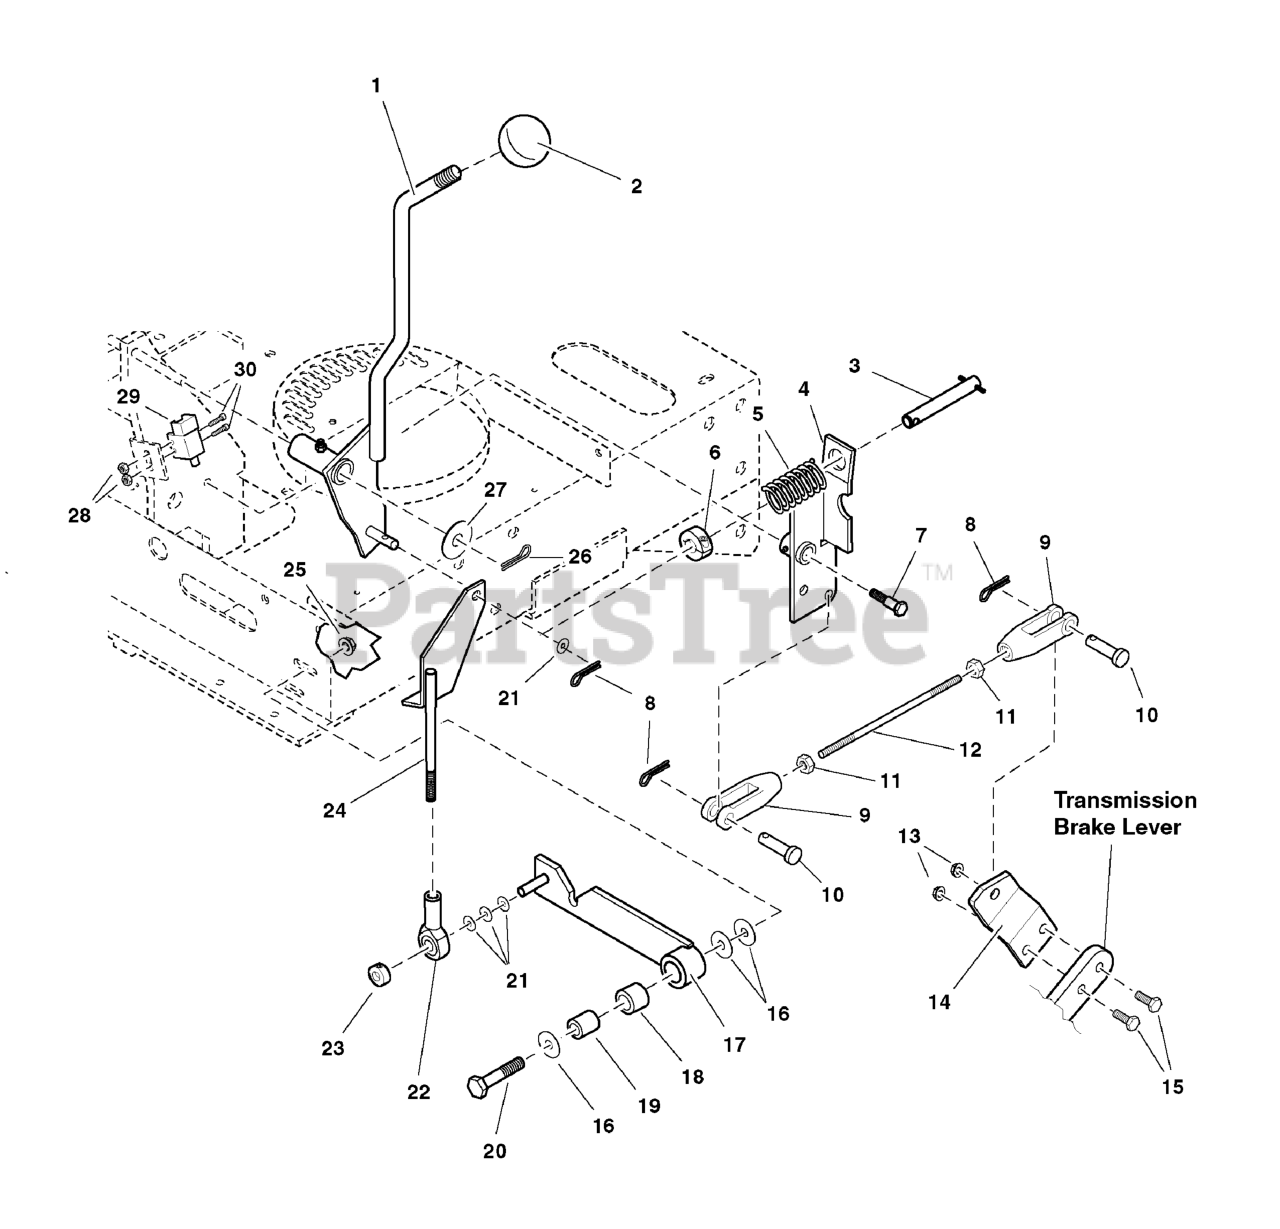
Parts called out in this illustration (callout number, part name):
1	PARKING BRAKE LEVER
2	KNOB
3	SPRING BAR ASSEMBLY
4	BRAKE ROCKER ARM
5	SPRING, Compression
6	COLLAR, 5/8" Set
7	SHOULDER BOLT, 1/2 x 1
8	PIN, 3/32 X 0.750, COT, ZINC/CLEAR
9	CLEVIS, 5/16-24, Plastic
10	CLEVIS PIN, 5/16 x 1
11	NUT, 5/16-24 Hex
12	BRAKE LINKAGE ROD
13	NUT, 1/4-20 HEX NYLON LOCK
14	BRAKE LEVER
15	BOLT, 1/4-20 X 1" GD5 CZ
16	WASHER, 5/16" Fender
17	NEUTRAL LOCK LEVER, Complete
18	BUSHING, Brass
19	SPACER, .32 x .75 x 1.06
20	BOLT, 5/16-18 x 2
21	WASHER, 5/16" SAE
22	BALL JOINT 5/16-24 RH FEMALE BRONZE RACE
23	COLLAR, 5/16" Set
24	BRAKE LOCK LINK
25	NUT, 5/16-18 HEX SERRATED FLANGE (LARGE)
26	PIN, COTTER, 1/8 X 1-1/4
27	WASHER, 5/8" SAE
28	NUT, #10-24 Hex
29	SWITCH, PLUNGER, N.O./N.C.
30	SCREW, #10-24 x 3/4
